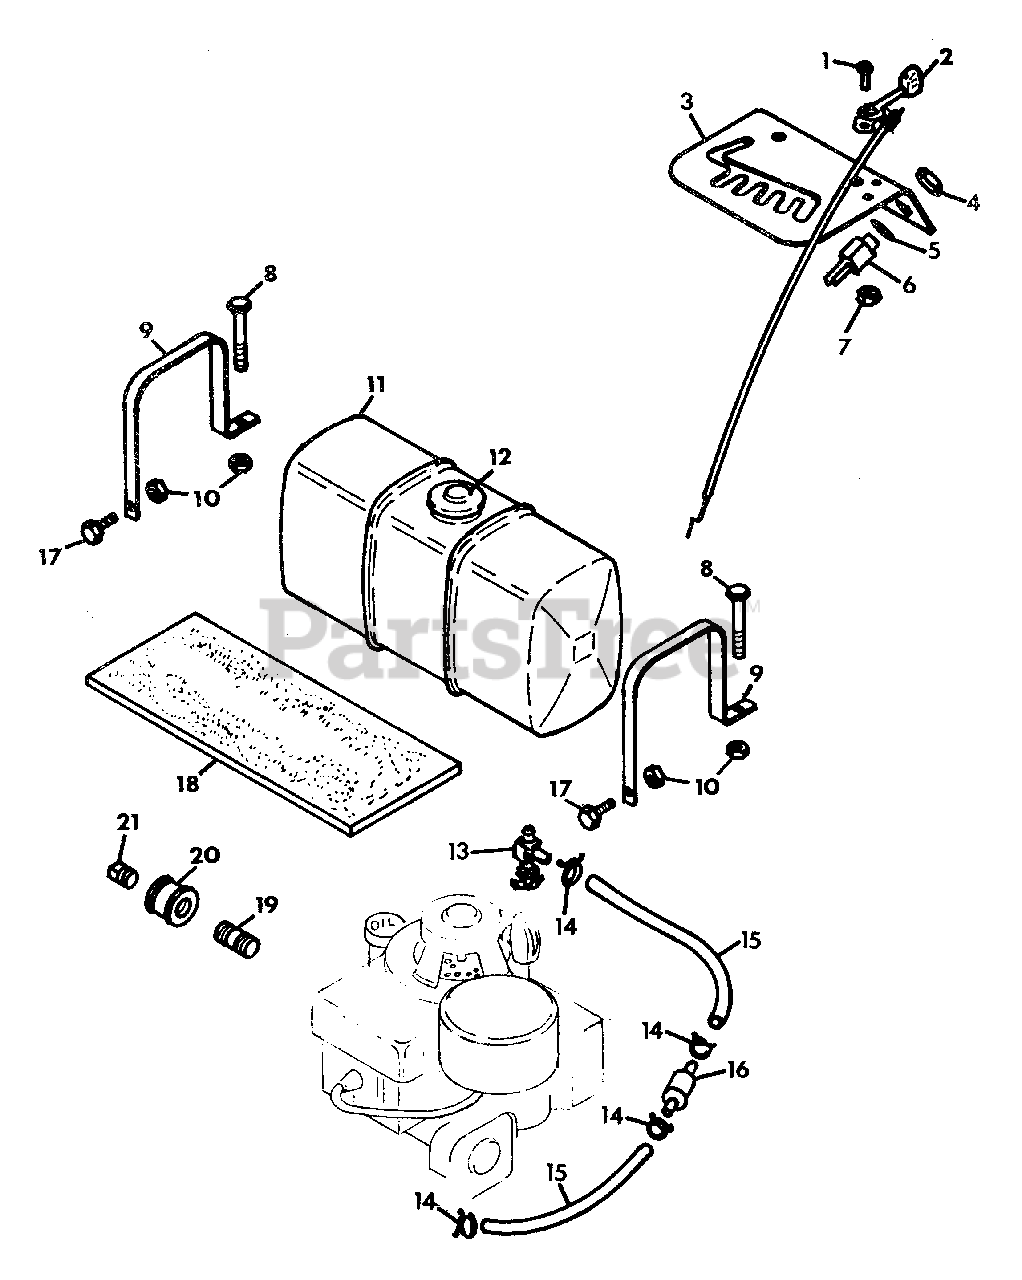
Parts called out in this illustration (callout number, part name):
1	Screw, Mach. 10-24x.50
2	Lever, Throttle-Choke
3	Plate, Instruction
4	Nut, Jam 5/8-32
5	Washer, Lock 5/8
6	Switch, Key
7	Nut, Lock 10-24
8	Bolt, Hex 1/4-20x2.75
9	Strap, Fuel Tank
10	Nut, Lock 1/4-20
11	Tank, Fuel (12 qts.)
12	Cap, Fuel Tank
13	Valve and Strainer
14	Clamp, Fuel Hose
15	Hose, Fuel
16	Filter, Fuel
17	Bolt, Hex 1/4-20x.625
18	Pad, Fuel Tank
19	Nipple, Pipe 3/8NPTx1.50
20	Coupling, Pipe 3/8N PT
21	Plug, Pipe 3/8NPT
